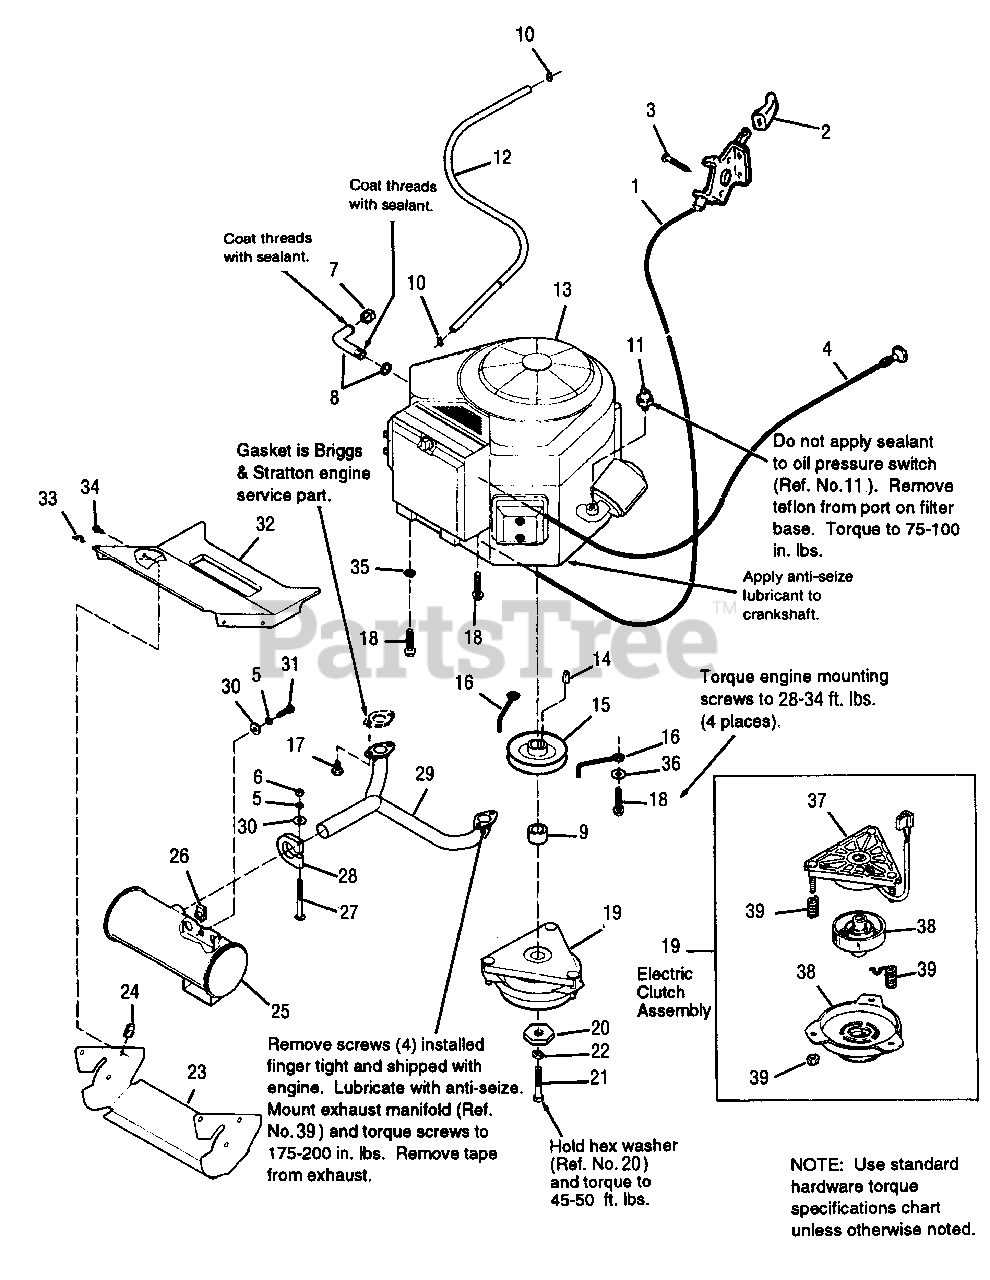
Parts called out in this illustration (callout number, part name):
1	THROTTLE & CABLE ASSY.
2	KNOB, Throttle
3	SCREW, Plastite, 1/4-10 x 1/2
4	CABLE, Choke Control
5	LOCKWASHER, 5/16
6	NUT, Hex, Full, 5/16-18
10	CLAMP, Hose
11	SWITCH, Oil Pressure
12	HOSE, Fuel, 45.5" Long
14	KEY, Hi-Pro
15	PULLEY ASSY. (All except Mfg. Nos. 1692301, 1692303, 1692438 & 1692444)
15	PULLEY ASSY. (Mfg. Nos. 1692301, 1692303, 1692438 & 1692444 Only)
17	SCREW, Metric
18	SCREW, Taptite, 3/8-16 x 1-1/2
19	ELECTRIC CLUTCH (Incl. Ref. Nos. 37-39)
21	CAPSCREW, 7/16-20 x 4
22	LOCKWASHER, 7/16
23	DUCT, Lower Muffler
24	NUT, Pal, 1/4-20
25	MUFFLER ASSY.
26	NUT, Pal, 5/16-18
27	CARRIAGE BOLT, 5/16-18 x 2-3/4
28	CLAMP, Muffler
29	MANIFOLD, Exhaust
30	WASHER, Plain, 11/32
31	CAPSCREW, Hex Hd., 5/16-18 x 1
32	DUCT, Upper Muffler
33	CLIP
34	SCREW, Flange Whiz, 1/4-20 x 5/8
35	LOCKWASHER, External Tooth
36	WASHER, Plain, 13/32
37	FIELD ASSY., Clutch
38	ROTOR ASSY./ARMATURE KIT
39	SPRING & NUT KIT
